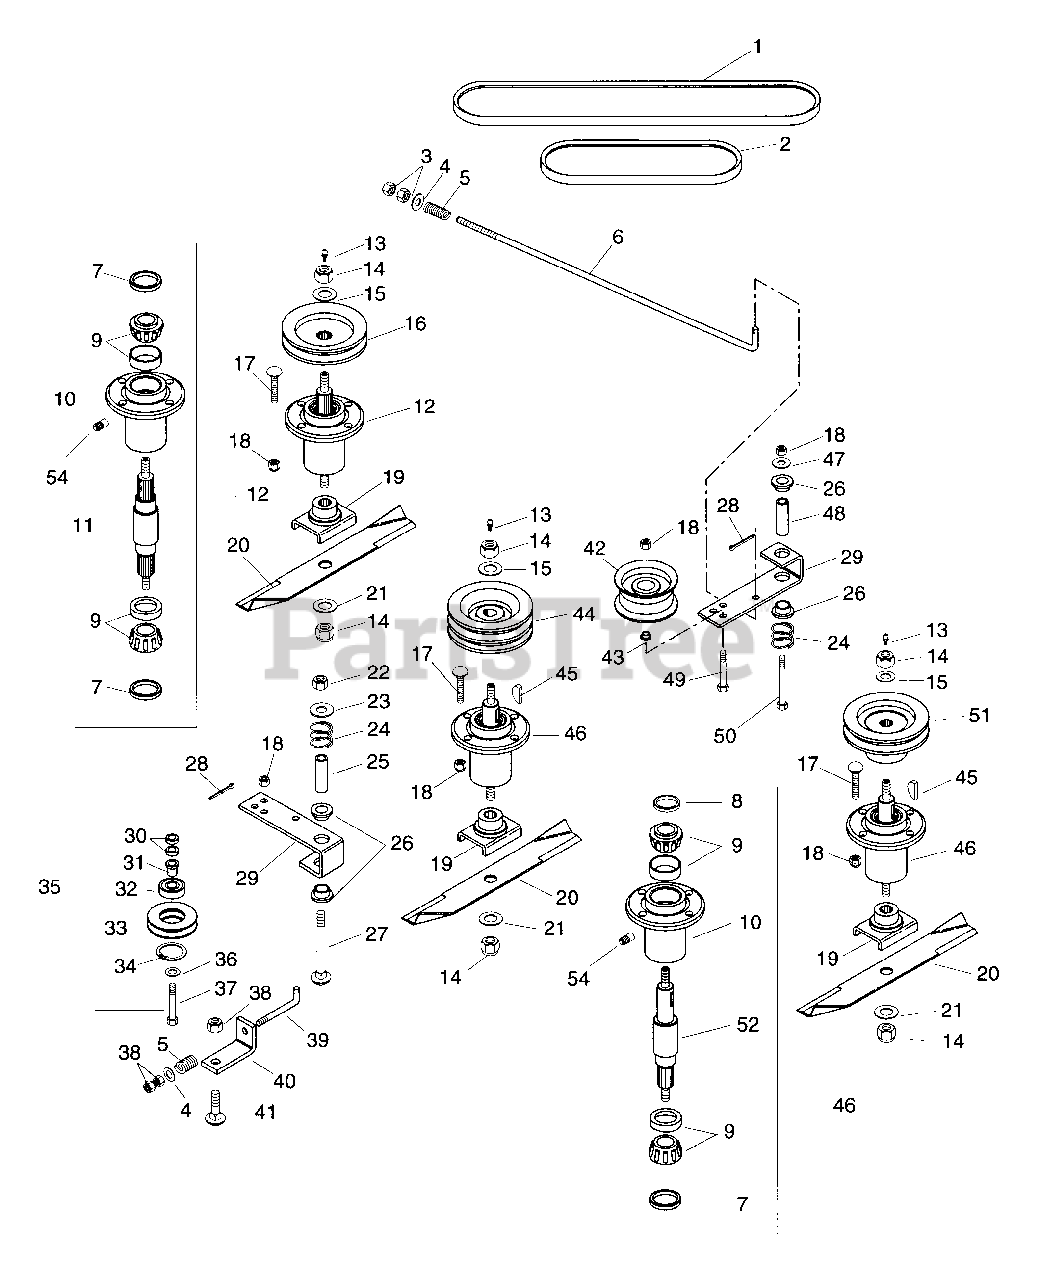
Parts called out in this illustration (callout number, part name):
1	V-Belt A-RMA 48.00 x .516/.031
2	V-Belt A-RMA 40.60 x .516/.031
3	Nut Hex .375 - 16
4	Wshr - Fl - Stl .281 x .625 x .065
5	Sg - Comp .188 x 1.66 x 2.0
6	Rod, Idler 25.0 Lg
7	Seal 1.987 x 1.375 x .313
8	Relief Fitting
9	Asm, Bearing Cup & Cone
10	Bearing Housing
11	Shft, Spindle
12	Service Kit Spindle Assembly
13	Ftg, Lube 1/8
14	Nut, Lk 5/8 - 11 Hex W/Insr
15	Wshr - Fl - Stl .687 x 1.312 x .135
16	Sheave, Spindle
17	Blt - Rdhdsqnk .38 - 16 x 1.375
18	Nut - Lk - Nyl .375 - 16 Pl
19	Weldment, Blade Cradle
20	Bld
21	Wshr - Fl - Stl .656 x 1.312 x .095 Pl
22	Nut - Lk .50 - 13 Hex Type N
23	Wshr - Fl - Stl .531 x 1.250 x .100
24	Sg - Comp
25	Bush., S .560 x .750 x 2.44 St
26	Bshg - Flg .762 x 1.0 x .580 x 1.48 NY
27	Blt - Rdhdsqnk .50 - 13 x 3.50
28	Pin - Cotr .09 x .75 Pl
29	Arm, Idler Pivot
30	Bushing .406 x .750 x .188
31	Bshg - Flg .786 x 1.0 x .79
32	Brg - Ball 1.85 x .787 x .55
33	Sheave, Idler
34	Rg - Rtng - Int 2.054 x .062
35	Asm, Idler Sheave
36	Washer, Flt .375 x 1.125 x .065
37	Blt - Hex .38 - 16 x 2.00 Pl Gr 5
38	Nut - Lk - Nyl .312-18 Pl
39	Rod, Idler
40	Brkt, Belt Tensioner
41	Blt - Rdhdsqnk .31-18 x 1.0
42	Idler - Flat 4 - .687 x .38
43	Bshg - Flg .406 x .88 x .270 x .140
44	Sheave
45	Key, Wdrf 1/4 x 1 Hrd #15
46	Service Kit Spindle Assembly
47	Wshr - Fl - Stl .438 x 1.000 x .083
48	Bush., S .437 x .750 x 2.44 St
49	Bit - Hex .38 - 16 x 2.25 Gr 5
50	Blt - Hex .38 - 16 x 3.25 Pl Gr 5
51	Sheave
52	Shft, Spindle
53	Seal 1.987 x 1.500 x .313
